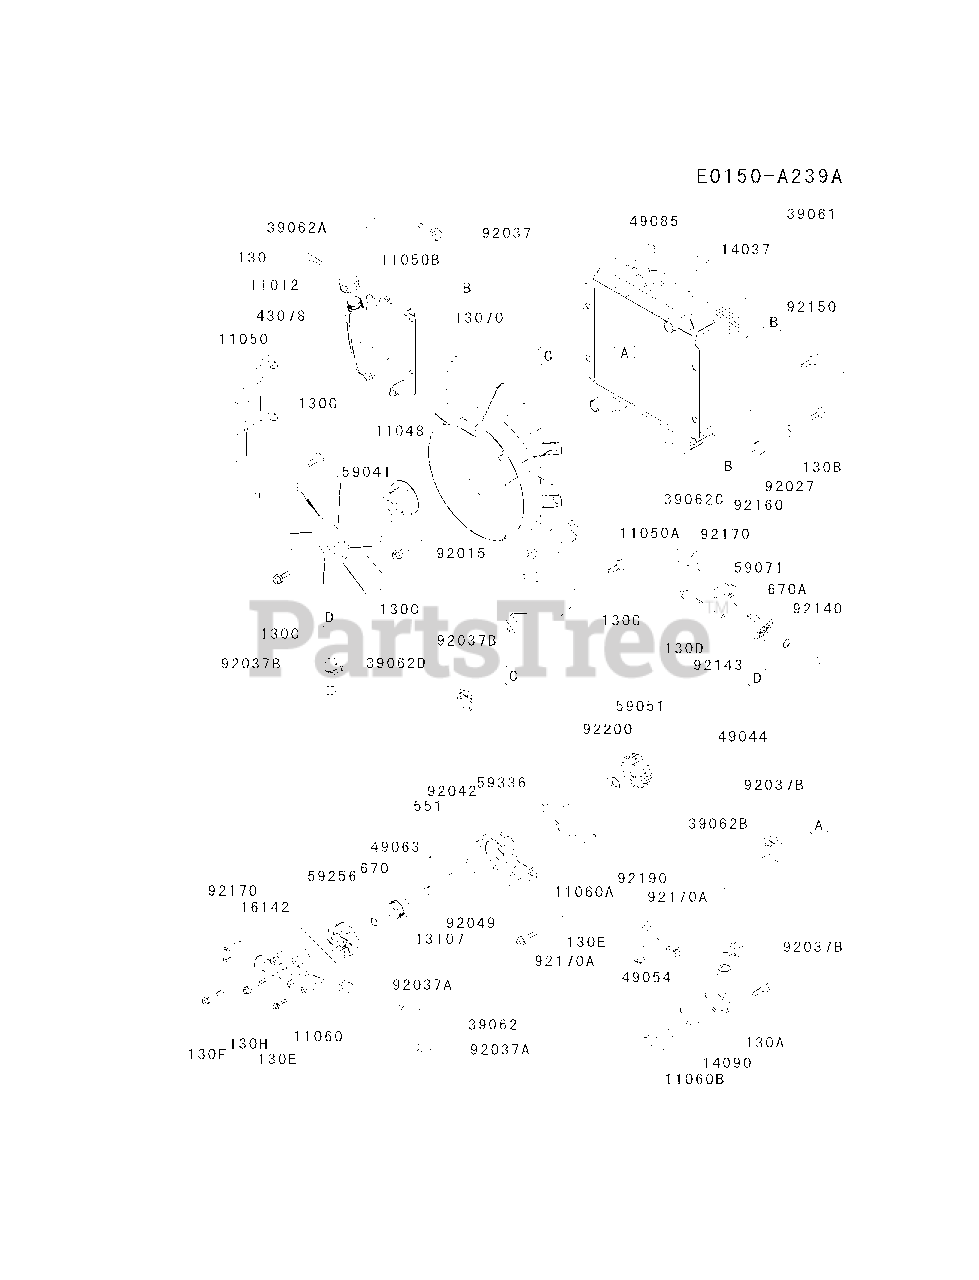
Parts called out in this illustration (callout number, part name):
130	BOLT-FLANGED
130A	BOLT-FLANGED
130B	BOLT-FLANGED
130C	BOLT-FLANGED
130D	BOLT-FLANGED
130E	BOLT-FLANGED
130F	BOLT-FLANGED
130G	BOLT-FLANGED
130H	BOLT-FLANGED
551	PIN-DOWEL
670	O RING
670A	O RING
92170	CLAMP
